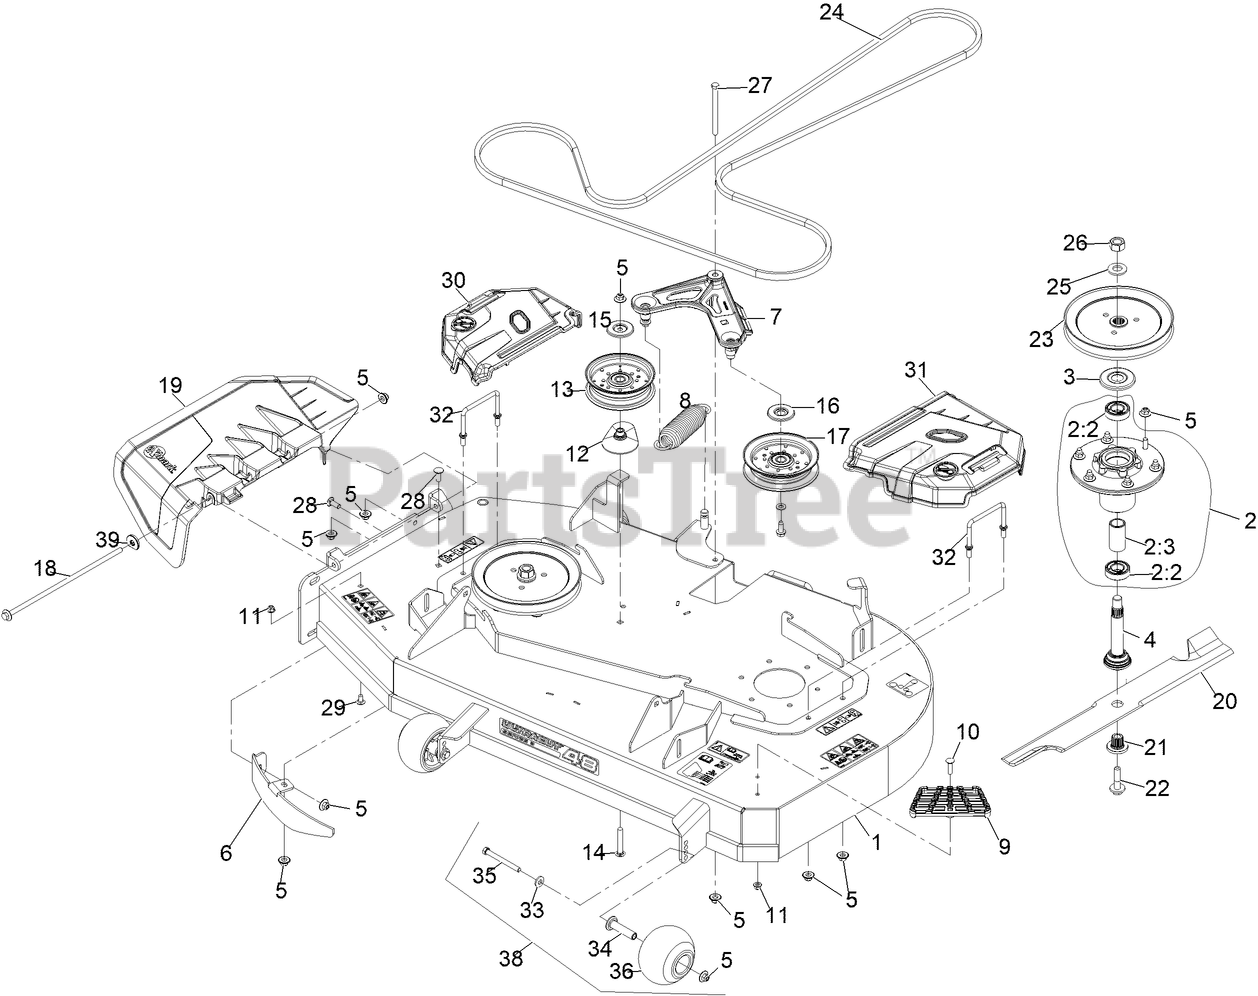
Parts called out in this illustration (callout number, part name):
1	ASM, 48" Deck W/Decals
2	ASM-CUTTER HSG WITH BEARINGS
2:2	BEARING-BALL
2:3	SPACER-BEARING
3	GUARD-BEARING, TOP
4	ASM-SPINDLE AND SEAL
5	Nut-Nyloc 3/8-16 Flg
6	Baffle-Discharge 48 2Blade
7	ASM-IDLER ARM W/BEARINGS
8	SPRING-EXTENSION
9	STEP-DECK
10	Bolt-Carriage 5/16-18 X 1 1/4
11	NUT-HF, NI
12	SPACER-PULLEY
13	IDLER-PULLEY, FLAT 5.00X1
14	SCREW-CARR
15	SHIELD-DUST
16	SHIELD-GUARD, DUST
17	IDLER-PULLEY, FLAT
18	Pin, Chute
19	Chute-Deck Discharge
21	BUSHING,SPLINED
22	SCREW,SEMS 1/2-20 X 2.19
23	SHEAVE-BLADE DRIVE, 8.40
24	BELT, B147.25
26	NUT-HEX
27	SCREW-HH
28	SCREW-CARR
29	SCREW-CARR
30	SHIELD, RT
31	SHIELD, LT
32	WIREFORM-COVER
33	WASHER-BELLEVILLE
34	AXLE, ROLLER
35	SCREW-HH 3/8-16 X 3 3/4 GR 8
36	ROLLER-SCALP, ANTI
38	KIT, ANTI-SCALP ROLLER
39	Retainer, Chute
